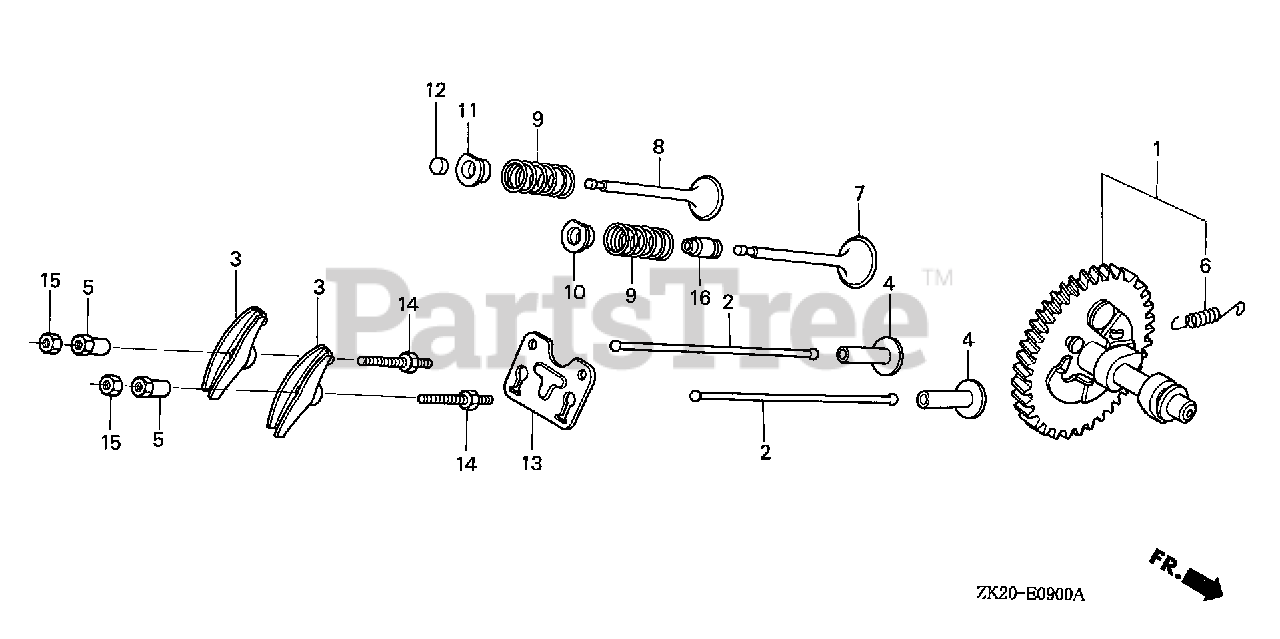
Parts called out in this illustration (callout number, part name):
1	CAMSHAFT ASSY.
3	ARM, VALVE ROCKER
4	LIFTER, VALVE
5	PIVOT, ROCKER ARM
6	SPRING, WEIGHT RETURN
7	VALVE, IN.
8	VALVE, EX. (STELLITE)
9	SPRING, VALVE
10	RETAINER, IN. VALVE SPRING
11	RETAINER, IN. VALVE SPRING
13	GUIDE, PUSH ROD
14	BOLT, PIVOT (8MM)
15	NUT, PIVOT ADJUSTING
16	SEAL, VALVE STEM
